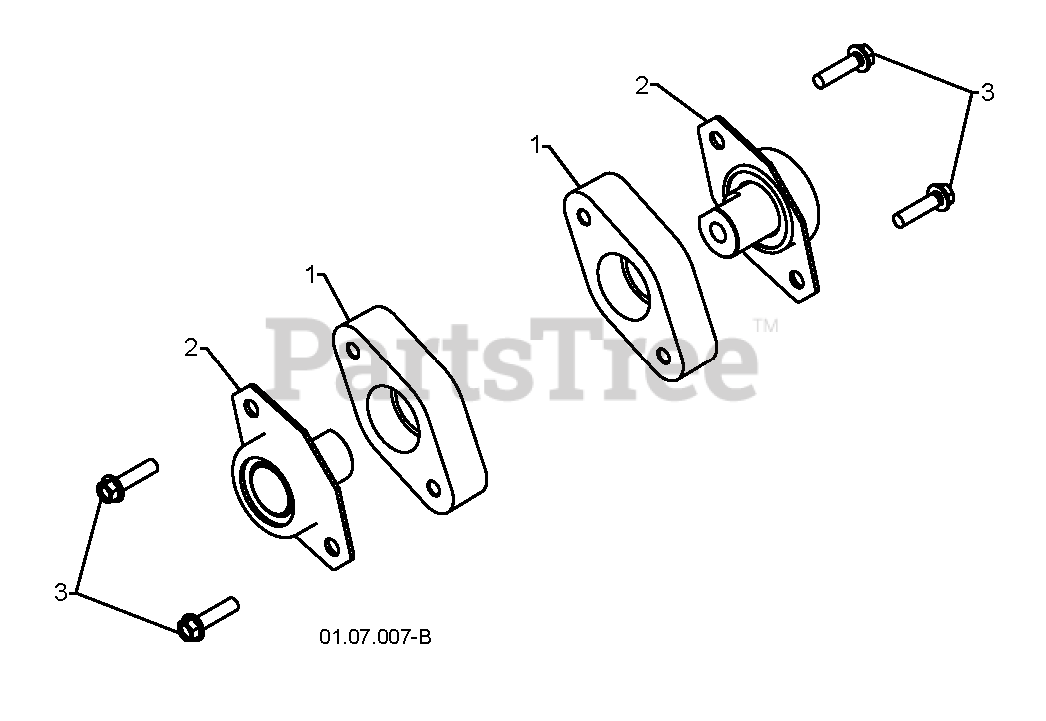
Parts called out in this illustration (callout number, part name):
1	RETAINER.PLASTIC
2	BEARING.BALL.AUGER
3	SCREW, HEX HD 5/16X1
